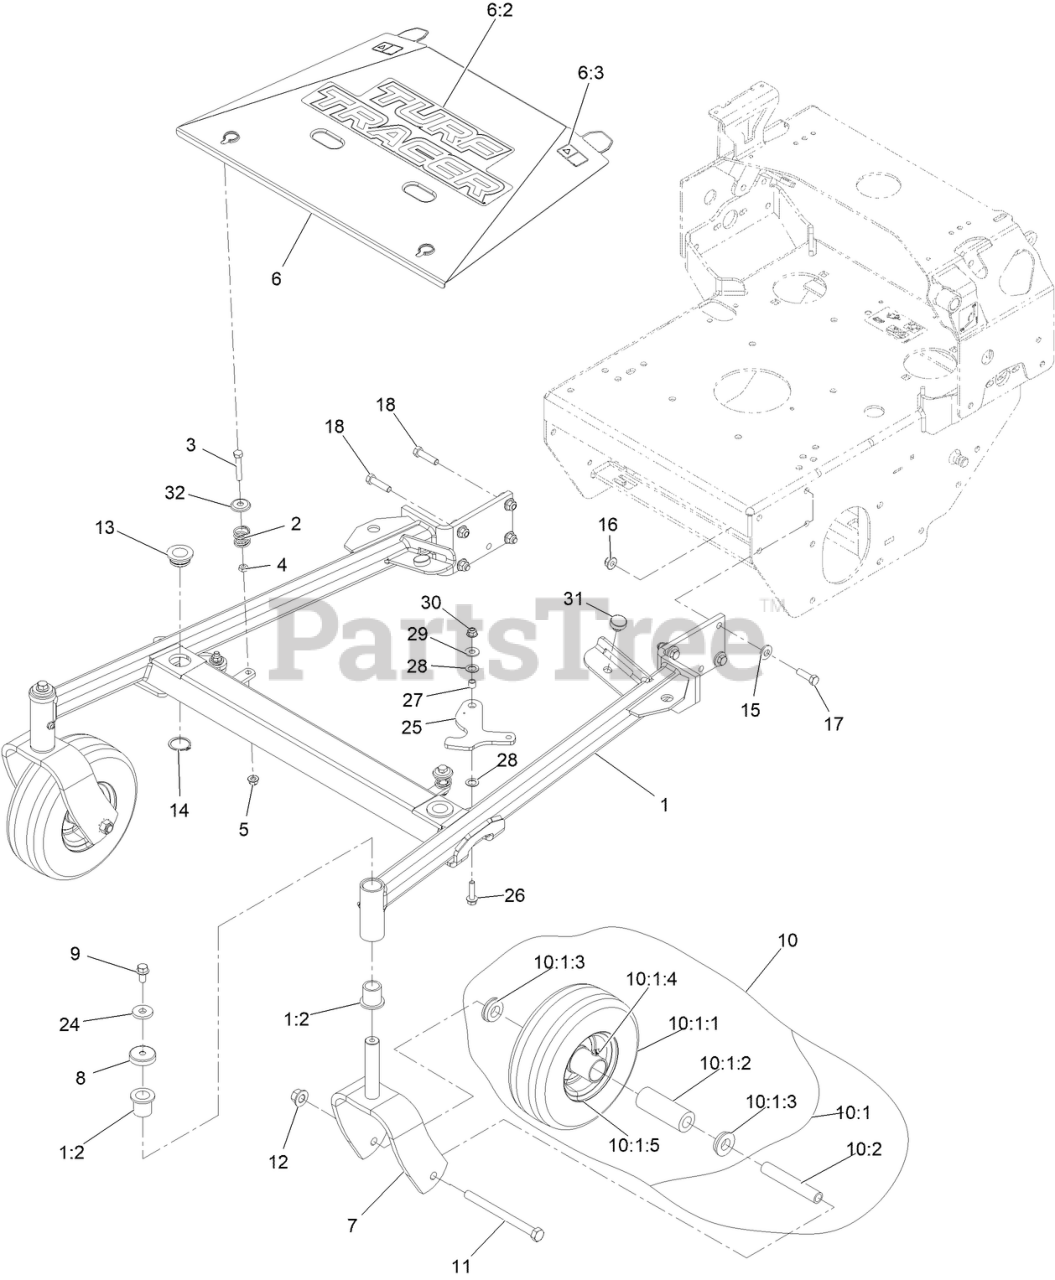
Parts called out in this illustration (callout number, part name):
1	ASM-48" Tts Front Frame
1:2	BEARING-FLANGED
3	SCREW-HH
4	NUT-JAM
5	NUT-HF, NI
6	ASM-48" Tts Center Shield
6:2	DECAL-TURF TRACER
6:3	DECAL-WARNING
7	FORK, CASTER
8	CAP, DUST
9	SCREW-HHF
10	KIT, SP CASTER WHEEL REPLACEMENT
10:1	Wheel And Tire ASM
10:1:1	Tire
10:1:2	BEARING
10:1:3	BUSHING
10:1:4	FITTING-GREASE
10:1:5	Wheel
11	SCREW-HH
12	Nut-Lock 1/2-13
13	BUSHING-DECK
14	RING-RETAINING
15	WASHER-BELLEVILLE
16	NUT-HF, NI
17	SCREW-HH
18	SCREW-HH
25	LATCH, DECK HEIGHT
26	Screw-HHF
27	Spacer-Grommet
28	WASHER-CONICAL
29	WASHER-FLAT
30	NUT-HF, NI
31	BUMPER-RUBBER
32	Washer-Cup
